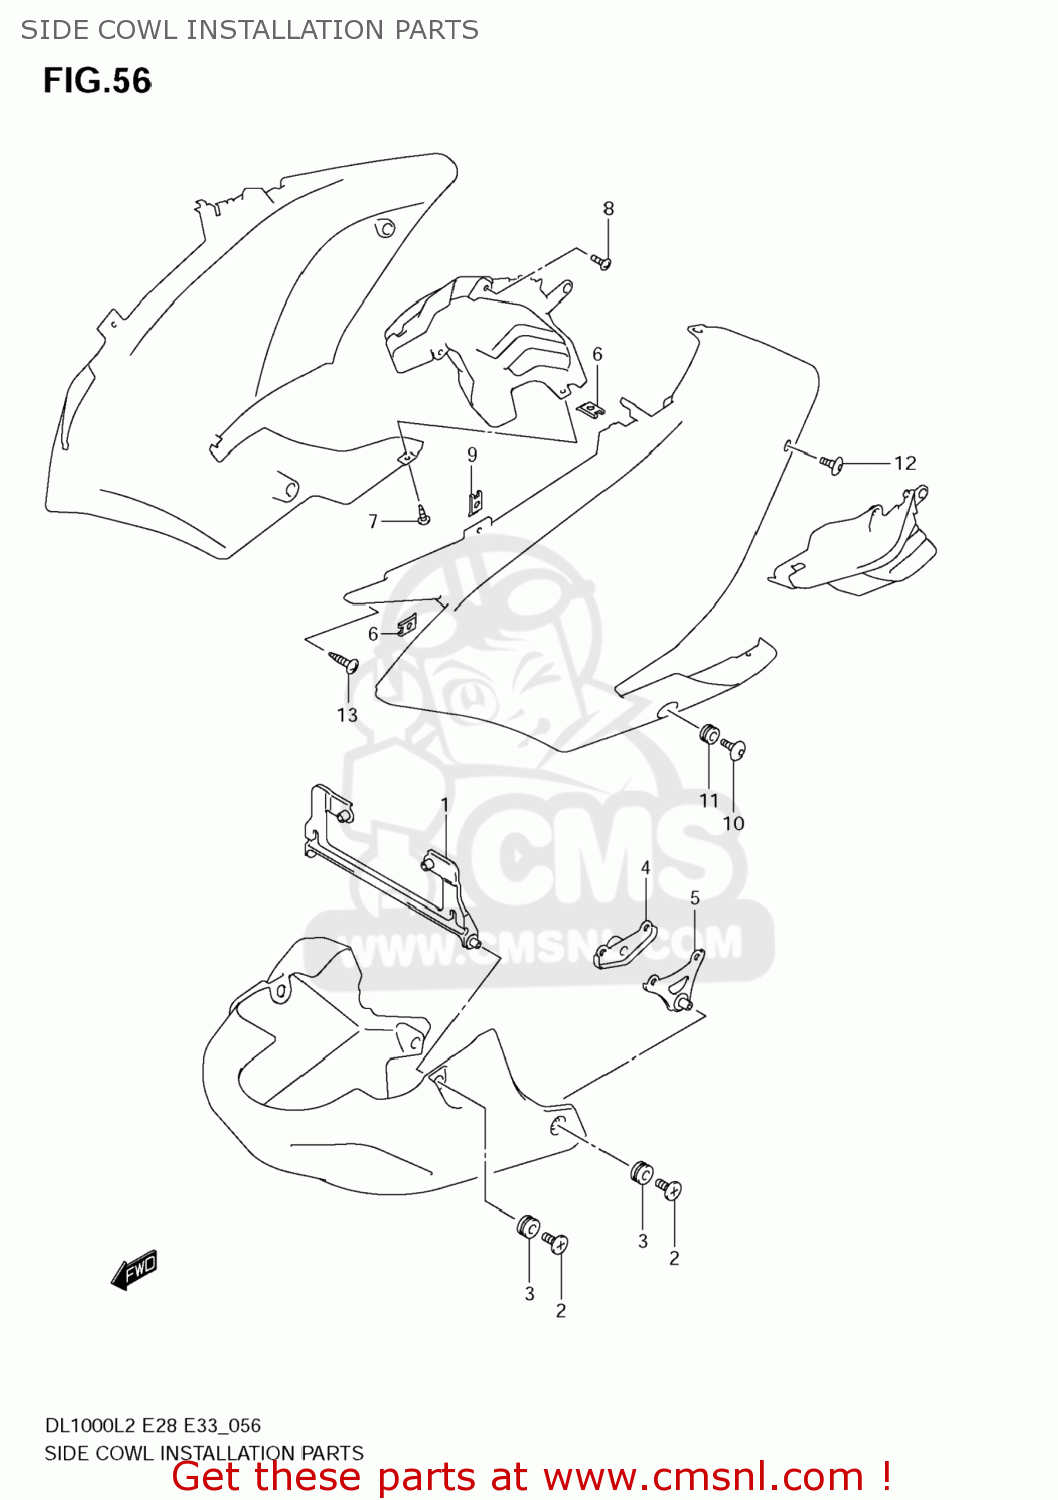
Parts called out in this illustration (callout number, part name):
1	BRACKET,UNDER COWLING FR
2	BOLT
3	CUSHION
4	BRACKET,UNDER COWLING,R
5	BRACKET,UNDER COWLING,L
6	NUT
7	SCREW
8	SCREW
9	NUT,COWL
10	SCREW(6X20)
11	CUSHION
12	SCREW(6X10)
13	SCREW
